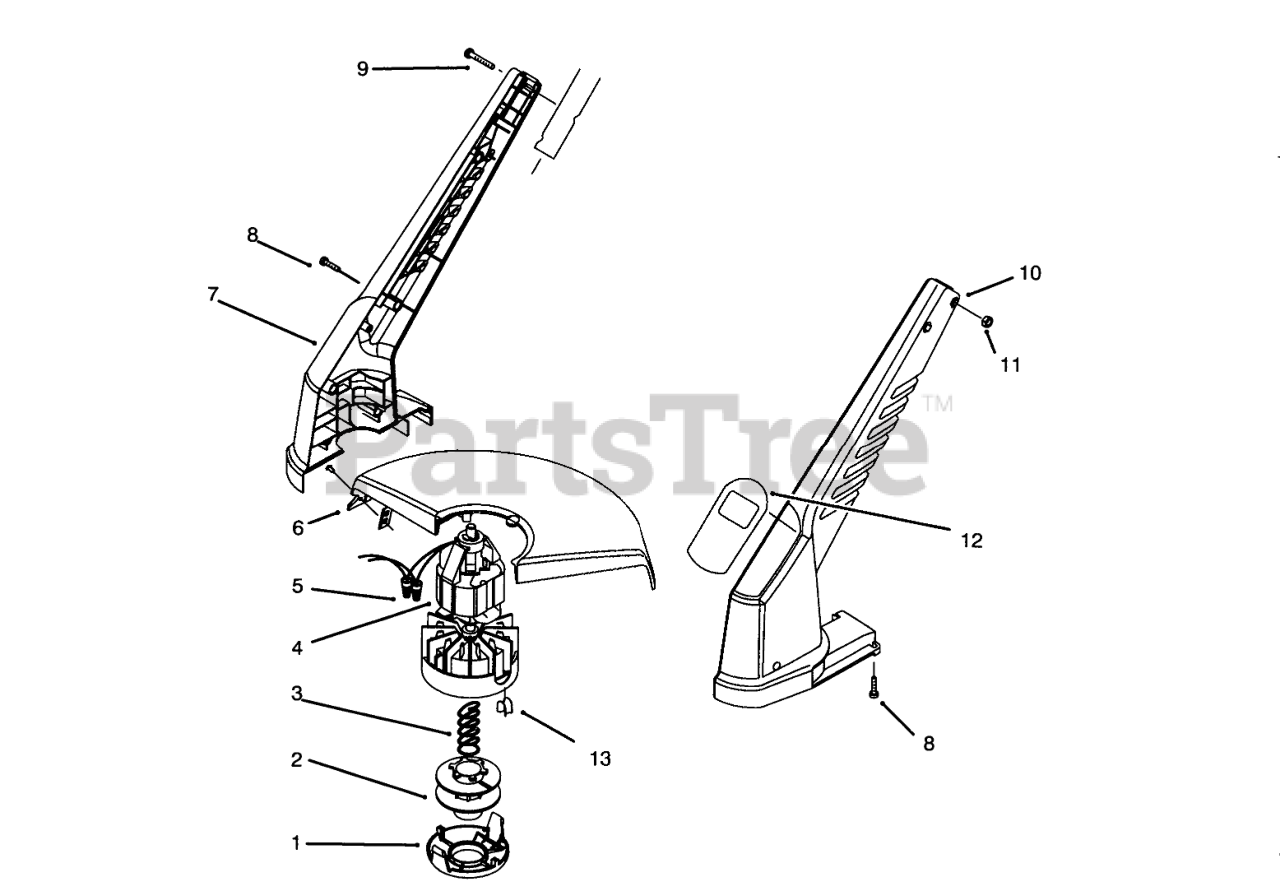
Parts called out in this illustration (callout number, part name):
2	SPOOL-LARGE
3	SPRING-COMPRESSION
4	Motor Assembly (Incl. Ret. #13)
5	CONNECTOR-NUT, WIRE
6	SHIELD ASM - SERVICE
7	RH HOUSING
9	SCREW-PPH
10	LH HOUSING
11	NUT-HEX
12	DECAL - 10" TRIMMER
13	EYELET
